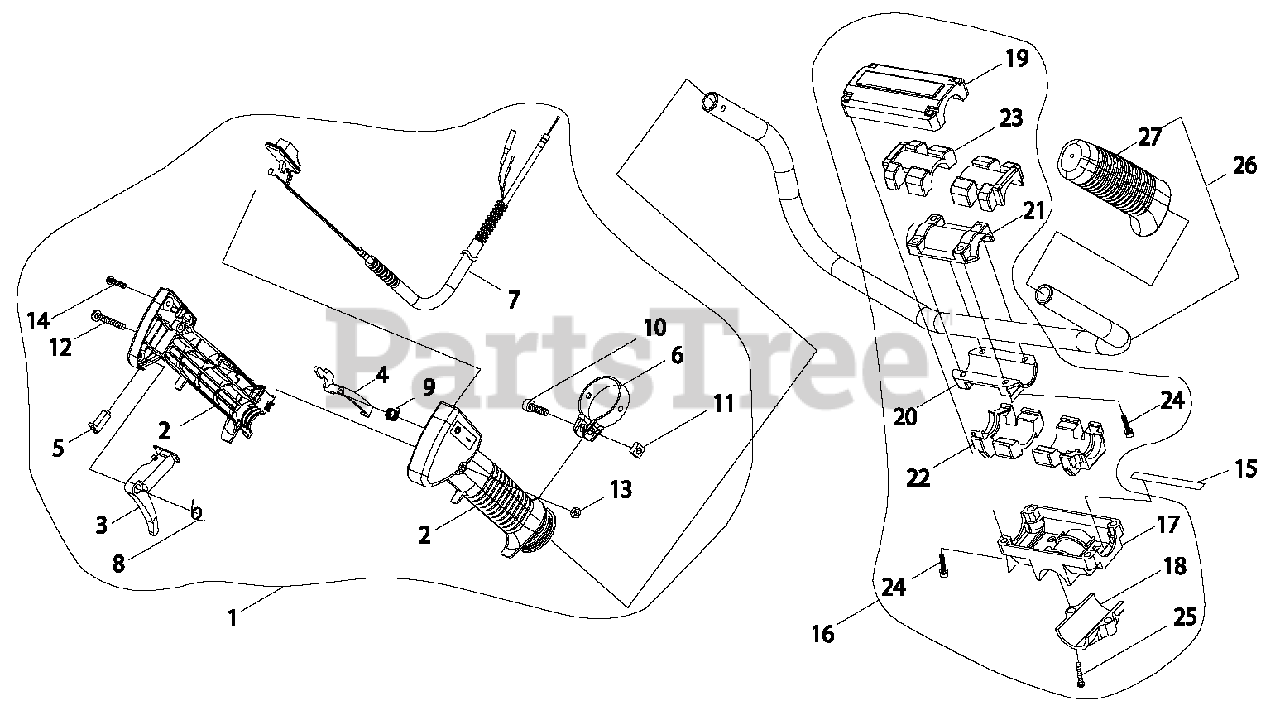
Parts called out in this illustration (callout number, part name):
1	CONTROL HANDLE KIT
2	CONTROL HANDLE ASSY
3	TRIGGER, THROTTLE
4	LEVER, LOCK
5	LOCK, THROTTLE
6	CLAMP
7	CONTROL CABLE ASSY
8	SPRING, RETURN
9	SPRING, LOCKOUT LEVER
10	SCREW - 6X20
11	NUT
12	SCREW - 5X35
13	NUT - 5
14	SCREW - TAPPING
15	LEAD - GROUND
16	HANDLE BRACKET KIT
17	BRACKET, HANDLE - LOWER
18	BRACKET, MOUNTING
19	BRACKET, HANDLE - UPPER
20	CLAMP - LOWER
21	CLAMP - UPPER
22	CUSHION - LOWER
23	CUSHION - UPPER
24	SCREW - 5X25
25	SCREW - 6X25
26	HANDLE KIT
27	GRIP
